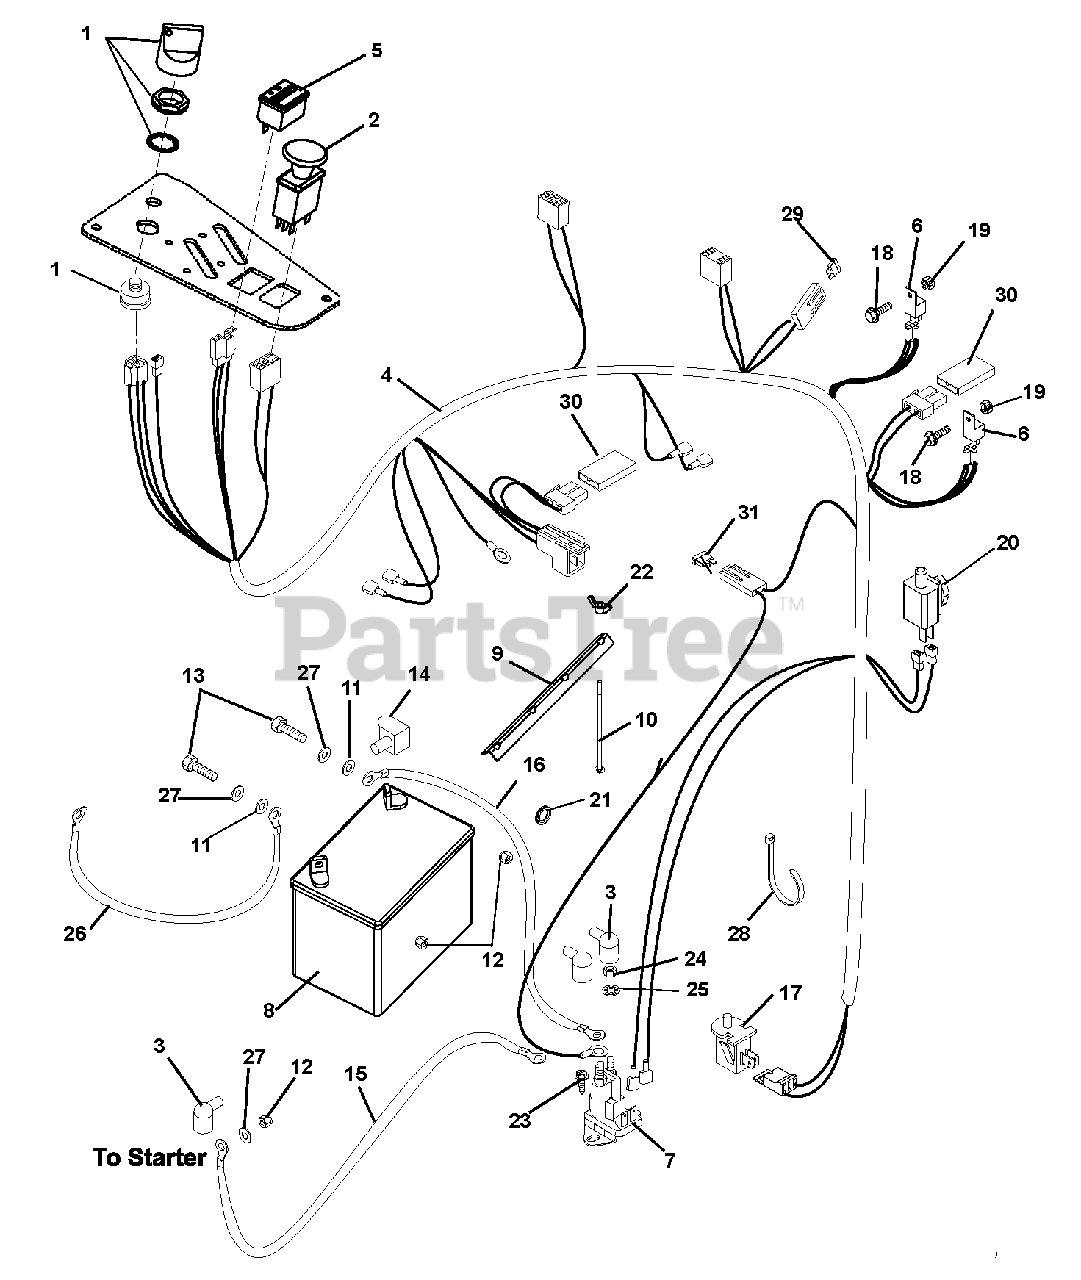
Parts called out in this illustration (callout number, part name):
1	Key Switch
2	PTO Switch
3	Boot, Eyelet Terminal
4	Harness- CZ Remote SOL.
5	Hour Meter – Digital
6	Relay, Sealed W/Diode
7	Solenoid
9	Hold Down
10	Bolt, Round Head Square Neck .25-20 x 7.50
11	Washer, Flat Steel .281 x .620 x .065
12	Nut, Hex .25-20
13	Bolt, Hex .25-20 x .75 Grade 5
14	Insulator
15	Cable, Positive Battery 9.00"
16	Cable, Negative Battery
17	Switch, Snap Mounting (N.O.)
18	Screw, Machine 10-24 x .50 Hex Washer Head
19	Nut, Locking Nylon 10-24 With Insert
20	Switch, Single Pole (N.O.)
21	Grommet, 2.12"ID .12"Groove Width, 2.50"Groove Diameter
22	Nut, Locking Wing .25-20
23	Screw, Tapping .25-20 x .50 Hex Washer Head
24	Nut, Jam .31-24
25	Washer, Locking .31 x .078 Regular
26	Cable, Starter
27	Washer, Lock .25 x .062
28	Tie, Cable LG 5.50
29	Fuse 20AMP
30	Diode, Connector Shell
31	Fuse-25 AMP
